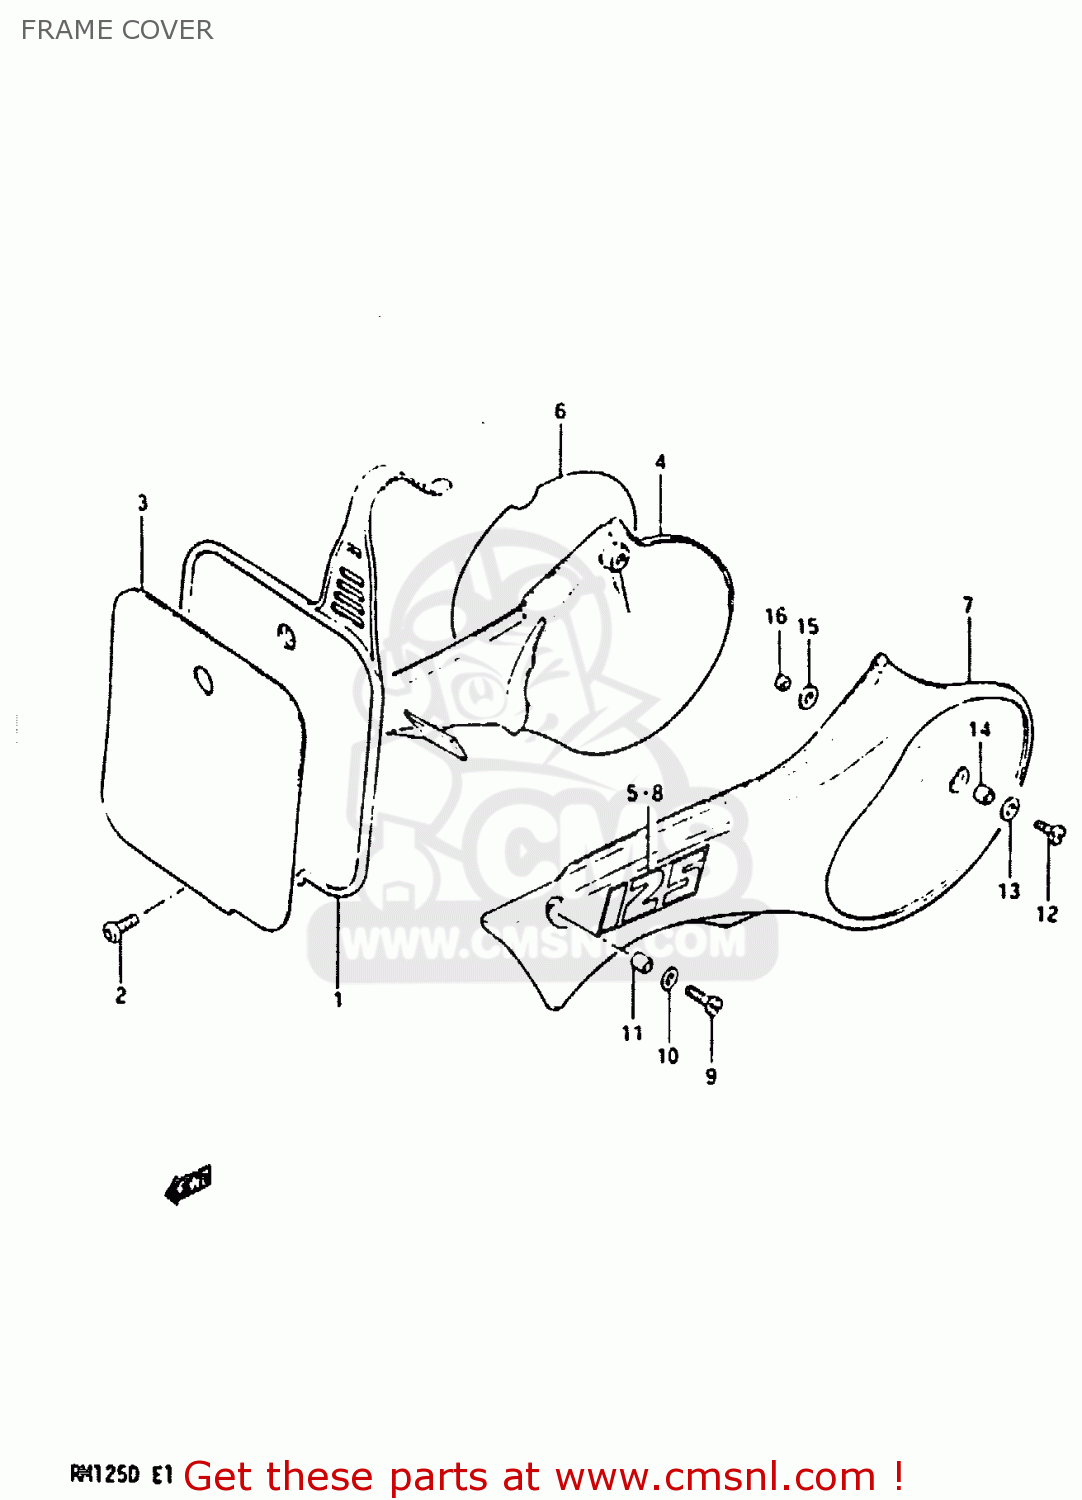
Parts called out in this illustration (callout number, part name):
1	PLATE,NUMBER,FRONT
2	SCREW
3	EMBLEM,FRONT NUMBER PLATE
4	COVER,FRAME,R(YELLOW)
5	EMBLEM,FRAME COVER,RIGHT
6	EMBLEM,FRAME COVER NUMBER
7	COVER,FRAME,LEFT
8	EMBLEM,FRAME COVER,LEFT
9	SCREW(6X14)
10	WASHER, REAR
11	SPACER(6.1X8X12.5)
12	SCREW(6X14)
13	WASHER, REAR
14	SPACER
15	GASKET
16	SPACER (6.1X8X3.5)
